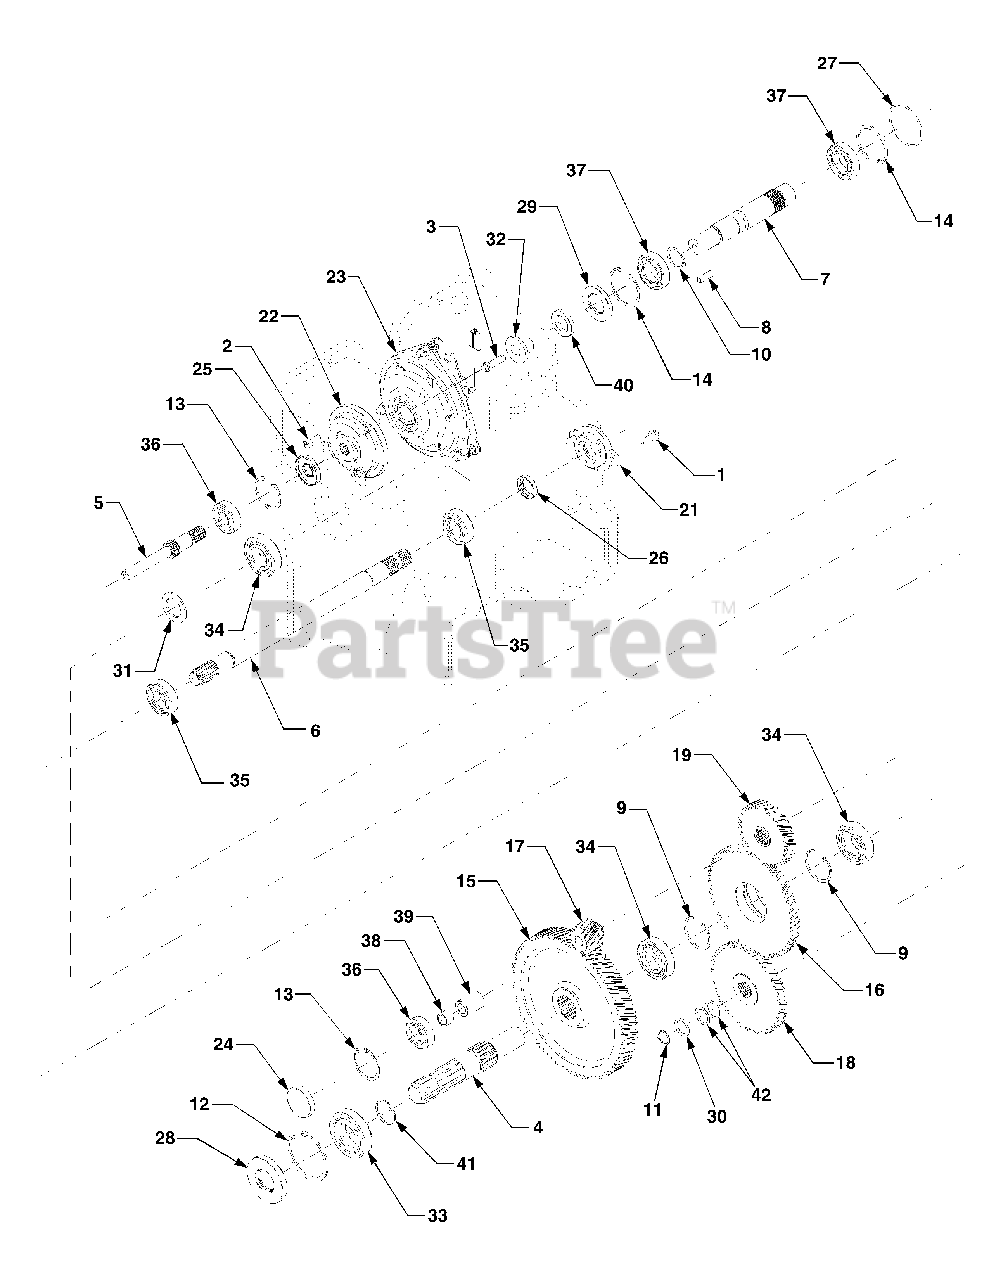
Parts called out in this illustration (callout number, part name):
1	Screw, Hex Wash. Hd. Tapp. 5/16-18 x .875
2	Screw, Socket Hd.5/16-18 x .75
3	Screw, 12 Pt. Wash. Hd. w/Patch 3/8-16 x 1.25
4	Shaft, 540 PTO
5	Shaft, Clutch Back
6	Shaft, 2000 PTO
7	Shaft, Input PTO
8	Key, Square, 1/4 x 1. 0
9	Ring, Retaining
10	Ring, Retaining
11	Ring, Retaining
12	Ring, Retaining
13	Ring, Retaining
14	Ring, Retaining
15	Gear, 540 PTO, 81T
16	Gear, 2000 PTO , 61T
17	Gear, Pinion, 540 PTO:14T
18	Gear, Pinion, 2000 PTO:54T
19	Gear, Pinion, 2000 PTO:34T
21	Cover, 2000 PTO
22	Adapter, PTO Output
23	Clutch Assy. PTO
24	Plug, Oil, 1.875 x .375
26	Seal, Oil
27	O-Ring, 2.425 ID x .103
28	Seal, Oil
29	Seal, Oil
30	Washer, Flat, .865 x 1.145 x .030 ..
31	Washer, Thrust
32	Spacer, Shoulder
33	Bearing, Ball
34	Bearing, Ball
35	Bearing, Ball
36	Bearing, Ball
37	Bearing, Ball
38	Spacer, 15mm x 20mm x 14mm
39	Spacer, .6 x 1.0 x 1.345
40	Spacer, 1.004 x 1.375 x .25
41	Ring, Retaining
42	Washer, Flat, .915 x 1.37 x .010
